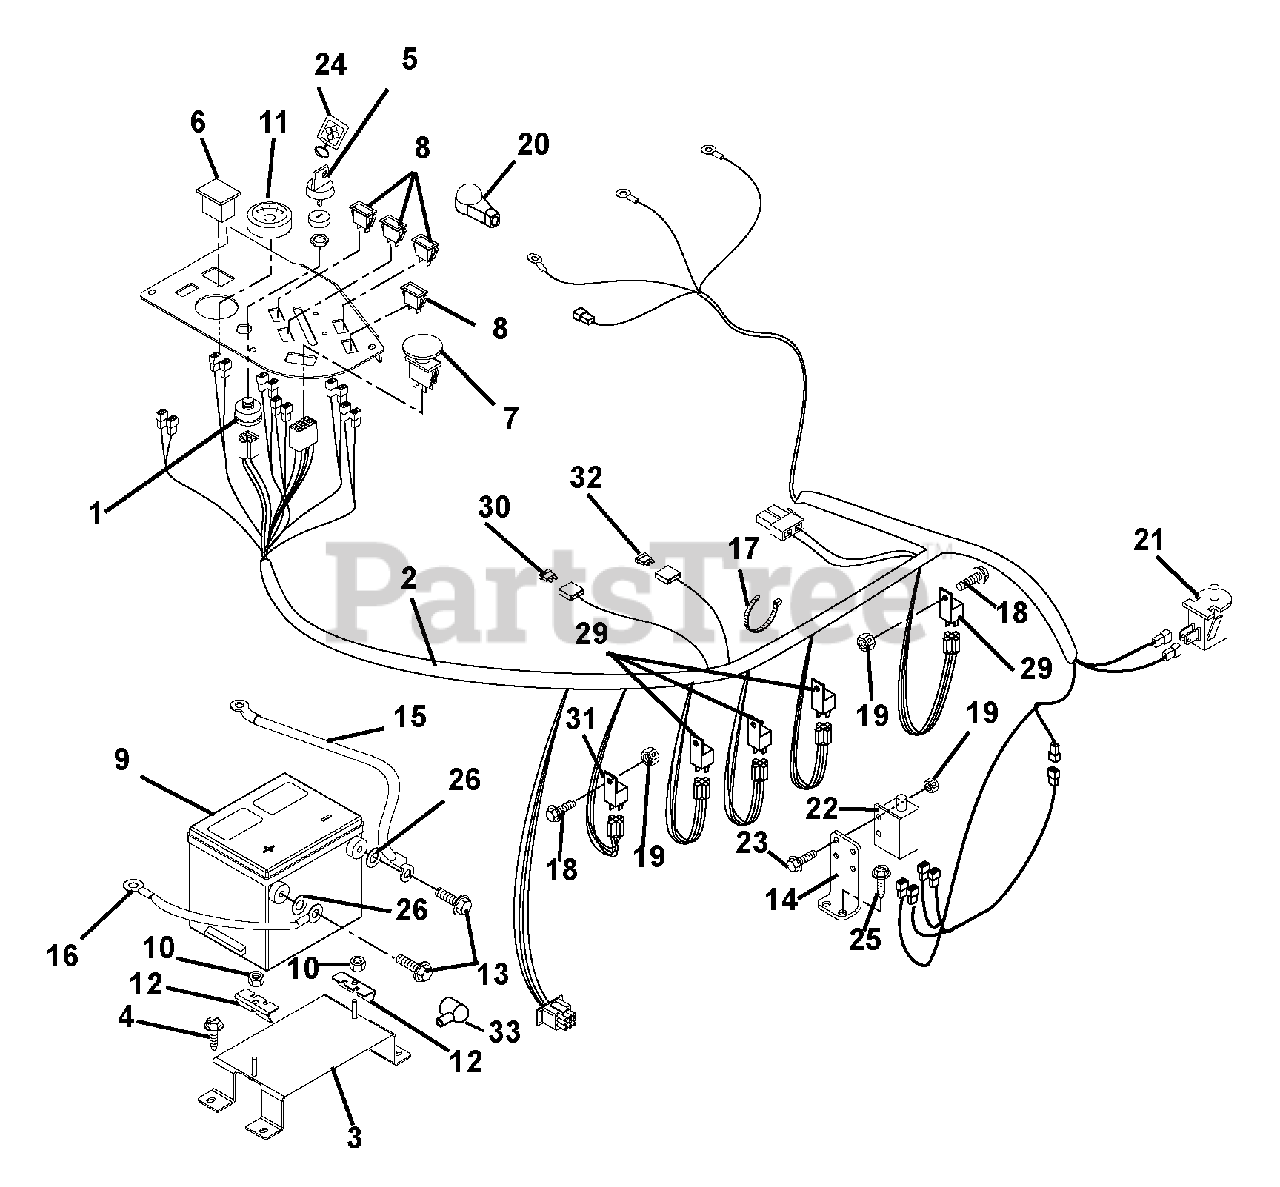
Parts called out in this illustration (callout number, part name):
1	Switch, Ignition
2	Harness, Wiring
3	Weldment, Battery Support
4	Screw-Tapping .38-16 x .75 Hex Washer Head
5	Key-with Cap
5	Ignition Key Set
6	Hour Meter
7	Switch-Clutch With Retainer Ring
8	Light-Indicator
9	Battery with Tube
10	Nut-Locking-Top-Flange .31-18
11	Gauge, Temperature
12	Bracket, Battery Hold-Down
13	Bolt-Hex .25-20 x .75 Grade 5
14	Mount, Safety Switch
15	Cable, Positive Battery with Boots
16	Cable, Negative Battery
17	Cable Tie
18	Screw-Machine 10-24 x .75 Hex Washer Head
19	Nut-Locking-Nylon 10-24 With Insert
20	Boot, Terminal - Red
21	Switch, Snap Mounting (N.O.)
22	Switch-Single Pole
23	Screw-Machine 10-24 x .75 Hex Washer Head
24	Key Chain
25	Screw-Tapping .25-20 x .50 Hex Washer Head
26	Washer-Flat-Steel .406 x 1.00 x ..083
27	Fuse, ATO 15 Amp
28	Diode, Connector Shell
29	Relay
30	Fuse, ATO 30 Amp
32	Fuse, ATO 60 Amp
33	Boot, Eyelet Terminal
